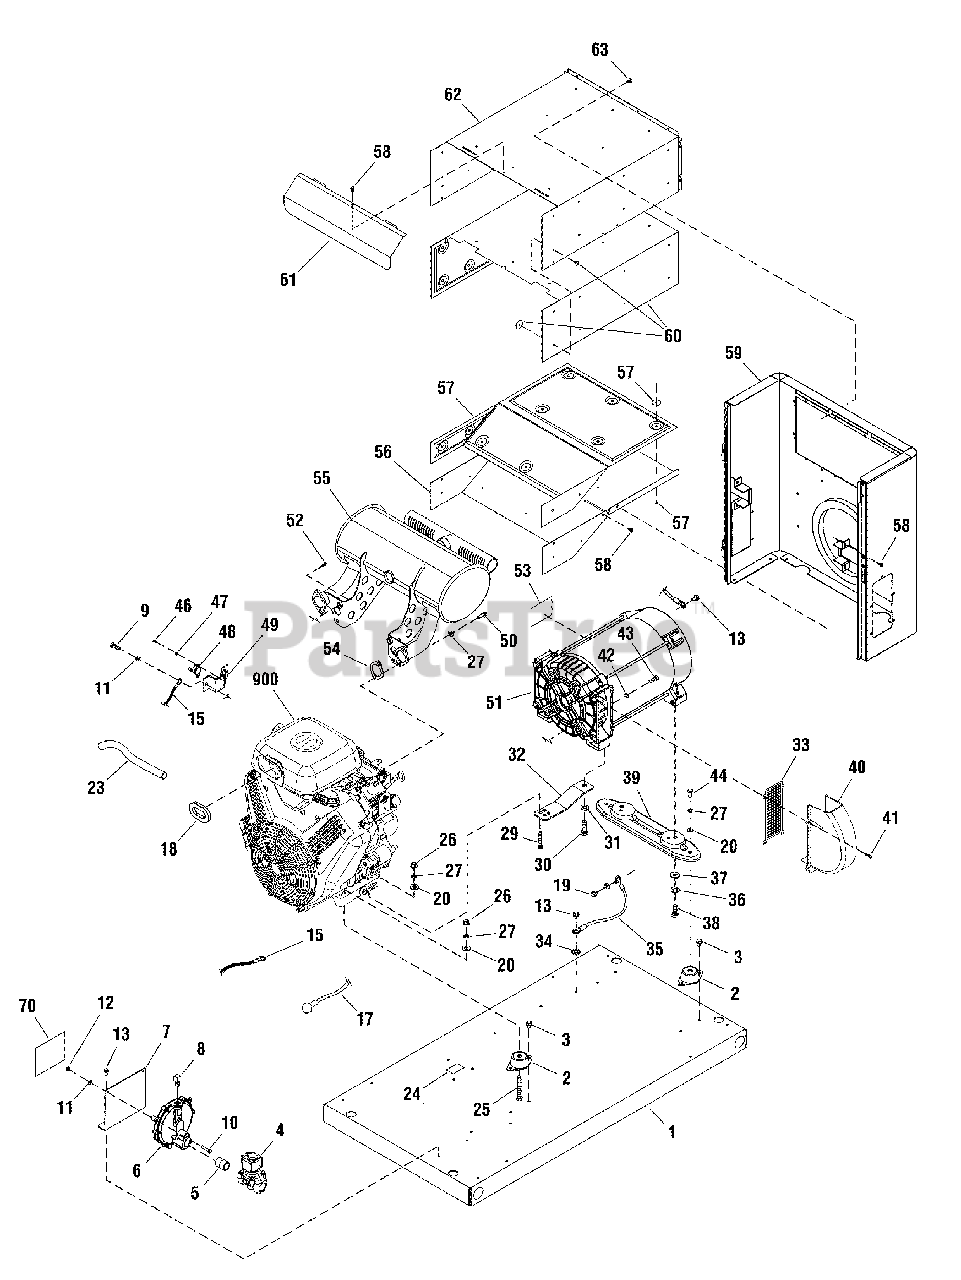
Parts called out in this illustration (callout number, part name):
1	BASE
2	MOUNT, Vibration
4	SOLENOID, Gas Fuel
6	REGULATOR, NG/LPG
9	* CAPSCREW, M6-1.0 x 16
10	* CAPSCREW, M6-1.0 x 30
11	* WASHER, Lock, 1/4
12	* NUT, M6-1.0
13	BOLT
15	CABLE, Battery, Black
17	CABLE, Battery, Red
18	SEAL, Foam
20	* WASHER, Flat, 5/16-M8
23	HOSE, Oil Drain
24	DECAL-OIL DRAIN
25	* CAPSCREW, Hex Head, 5/16-18 x 2-1/2
26	* NUT, 5/16-18
27	* WASHER, Lock, 5/16-M8
29	* CAPSCREW, Hex Head, 5/16-18 x 2
30	* CAPSCREW, Hex Head, M12-1.75 x 35
31	* WASHER, M12
32	SUPPORT, Engine
34	* WASHER, Shakeproof, M6-1/4
36	* WASHER, Lock, 3/8
37	* WASHER, Flat, 3/8
38	* CAPSCREW, Hex Head, 3/8-16 x 1
39	SUPPORT, Engine
41	* SCREW, Taptite, M5-0.8 x 10
42	* WASHER, Lock, 3/8
43	* CAPSCREW, Socket Head, 3/8-16 x 1-1/4
44	* CAPSCREW, Hex Head, 5/16-18 x 3/4
46	* SCREW, Pan Head, 4-40 x 0.19
47	* WASHER, Lock, #4
49	PLATE, Temp Switch
50	SCREW
51	ALTERNATOR
53	DECAL
59	BULKHEAD, Alternator
62	BOX, Muffler Top
900	** ENGINE
